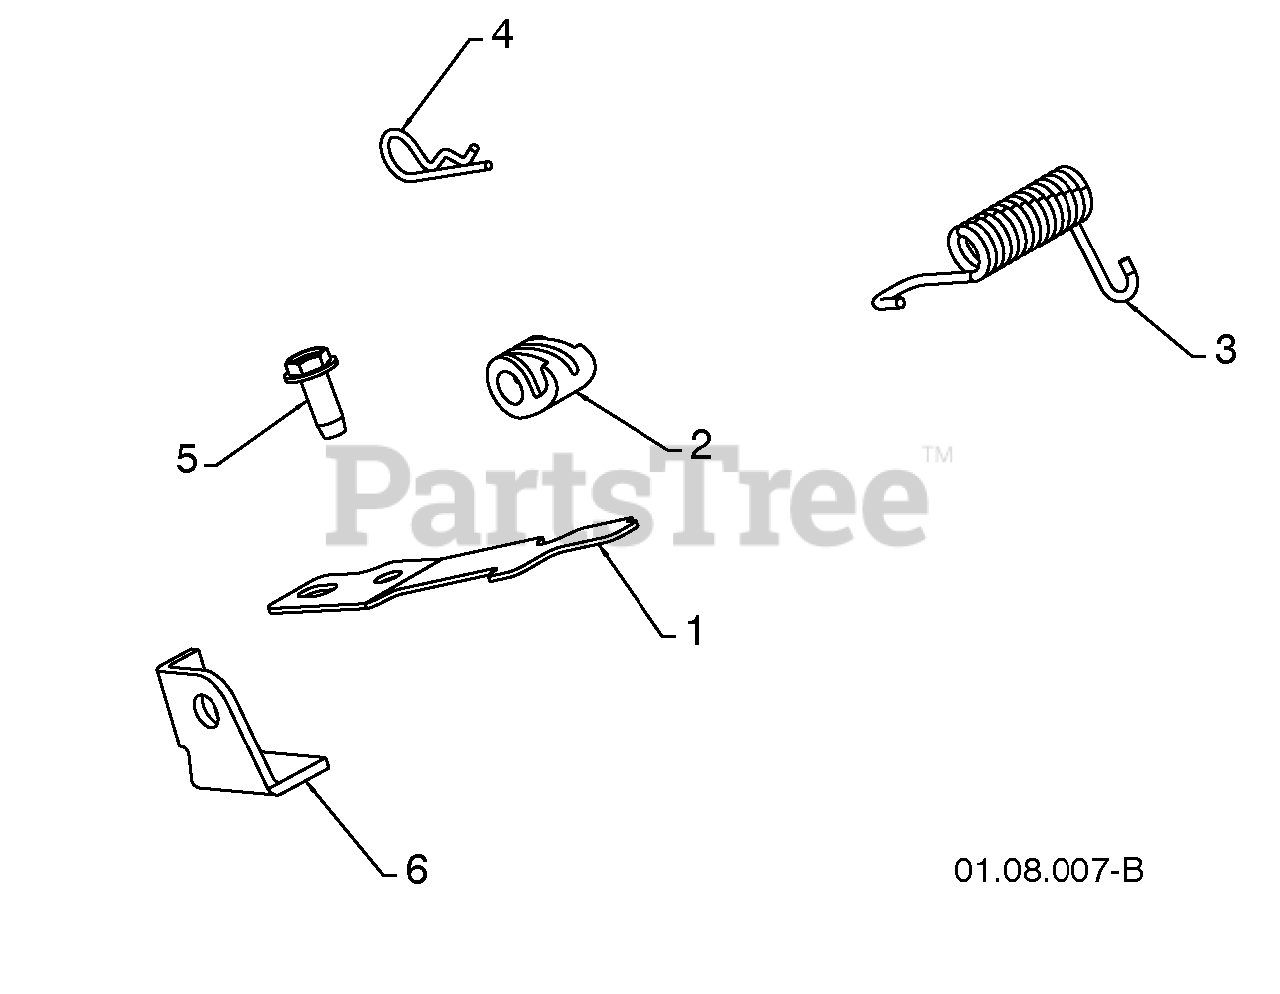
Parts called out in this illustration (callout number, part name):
1	INTERLOCK SPRING
2	INTERLOCK CAM
3	TORSION SPRING
4	RETAINER
5	SCREW 1/4-20 X .625
6	INTERLOCK STOP
